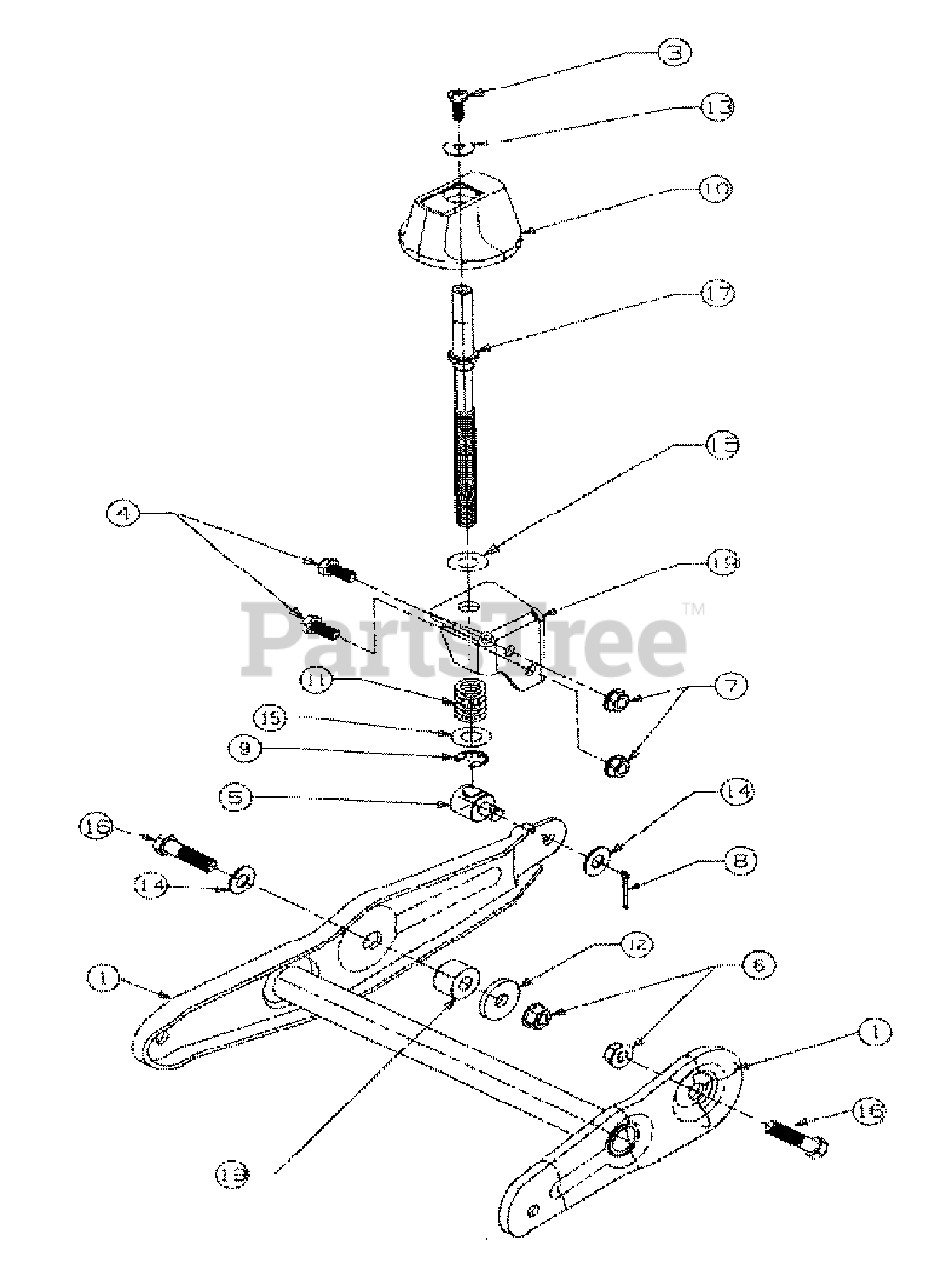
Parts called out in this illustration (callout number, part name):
4	SCREW-HEX
5	FERRULE-ADJUSTABLE
6	NUT-HEX FLANGE LOCK
7	NUT-HEX FLANGE
8	PIN-COTTER
9	RING-E
10	KNOB-PLASTIC
11	SPRING-COMPRESSION
12	WASHER-FLAT
13	WASHER-BELL
14	WASHER-FLAT
15	WASHER-FLAT
16	SCREW-SHOULDER
17	ROD-ADJUSTABLE
18	SPACER
